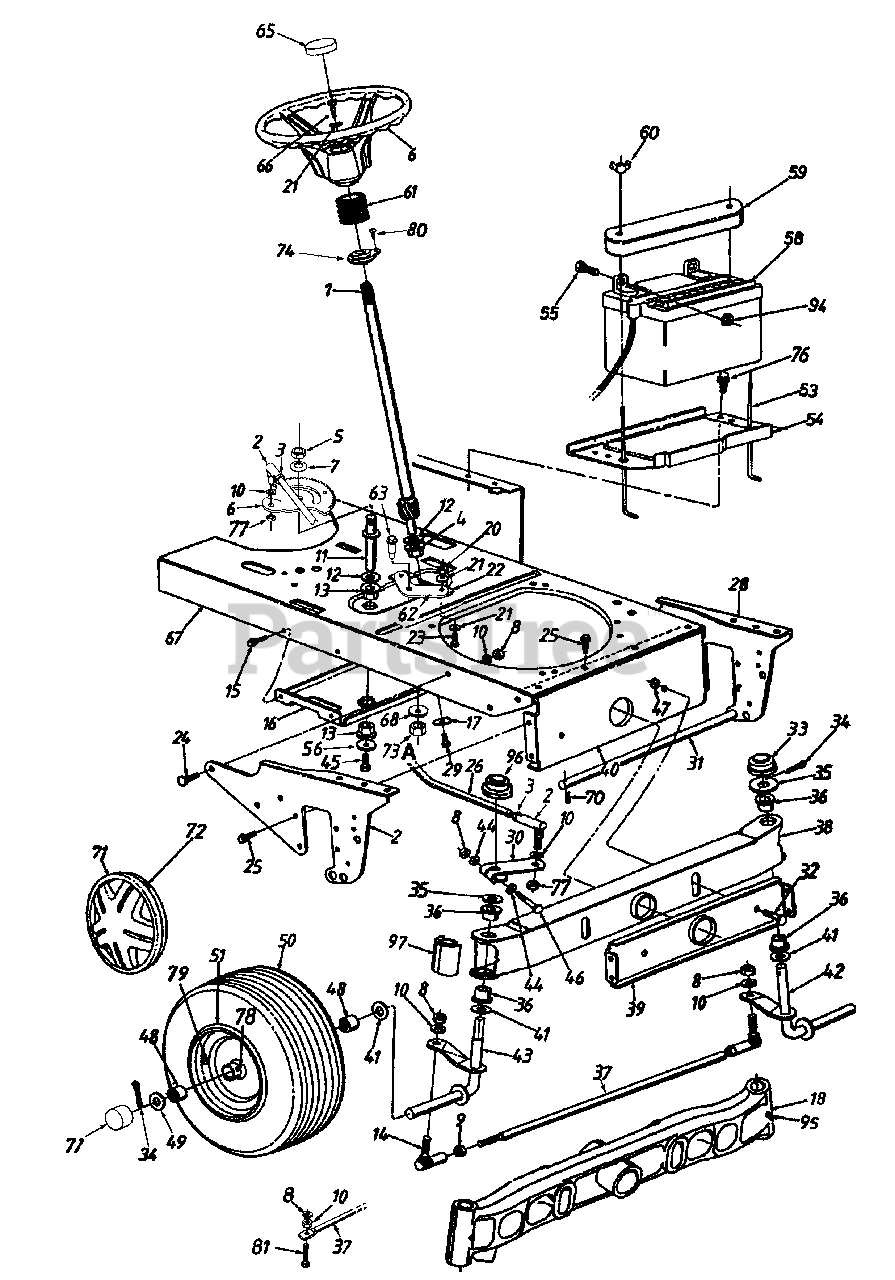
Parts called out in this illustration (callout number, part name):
1	Steering Shaft Ass'y.
2	Ball Joint 7/16-20 Thd.
3	Hex Jam Nut 7/16-20 Thd.
4	Hex Flange Brg.
5	Hex Jam Nut 5/8-18 Thd.
6	Steering Gear Segment
7	Bell-Wash. 5/8" I.D. x 1.25" O.D.
8	Hex Nut 3/8-24 Thd.
10	L-Wash. 3/8" I.D.
11	Steering Gear Segment Shaft
12	Fl-Wash. .64" I.D. x 1.24" O.D.
13	Hex Flange Brg. .63" I.D.
14	Ball Joint Ass'y.
15	Hx Wash. Hd. TT-Tap Scr. 1/4-20 x .5" Lg.
17	Cap
18	Pivot Bar Ass'y. (Cast Iron)
20	Hex Nut 5/16-24 Thd.
21	Bell-Wash. .345" I.D. x .88" O.D.
24	Ribbed Neck Bolt 3/8-24 x .8" Lg.
25	Hex Wash. TT-Tap Scr.5/16-18 x .62" Lg.
26	Steering Drag Link
31	Deck Connecting Rod
32	Shld. Bolt.498" Dia. x 2.45" Lg.
33	Cap
34	Cotter Pin 5/32" Dia.
35	Flat Washer
36	Flange Brg. .757" I.D.
37	Tie Rod (Adjustable)
41	Fl-Wash. .76" I.D. x 1.49" O.D.
42	Front Axle Ass'y.--L.H.
43	Front Axle Ass'y.--R.H.
44	Bowed Washer
45	Hex L-Scr. 5/16-18 x .62" Lg.
46	Hex Bolt 3/8-24 x 2.25" Lg.
47	Hex L-Nut 3/8-16 Thd.
48	Flange Brg. .75" I.D.
49	Fl-Wash. .71" I.D. x 1.5" O.D.
56	Fl-Wash. .33" I.D. x 1.25" O.D.
58	Battery
59	Battery Cover
60	Wing Nut Plastic 1/4-20 Thd.
61	Steering Bellow
65	Steering Cap (Round)
66	Hex L-Bolt 5/16-18 x 1" Lg.
70	Internal Cotter Pin
71	Hub Cap
72	Spring Clip
73	Hex Nut 3/8-16 Thd.
74	Flange Bearing
76	Hex Wash. B-Tap Scr. 1/4 x .62" Lg.
77	Hex Jam L-Nut 3/8-24 Thd.
78	Grease Fitting
79	Air Valve
80	Oval Hd. Cr.-Sunk Scr. #10 x 5/8" Lg.
81	Hex Bolt 3/8-24 x 1.5" Lg. (Gr. 5)
94	Hex L-Nut 1/4-20 Thd.
95	Grease Fitting
97	End Cap
